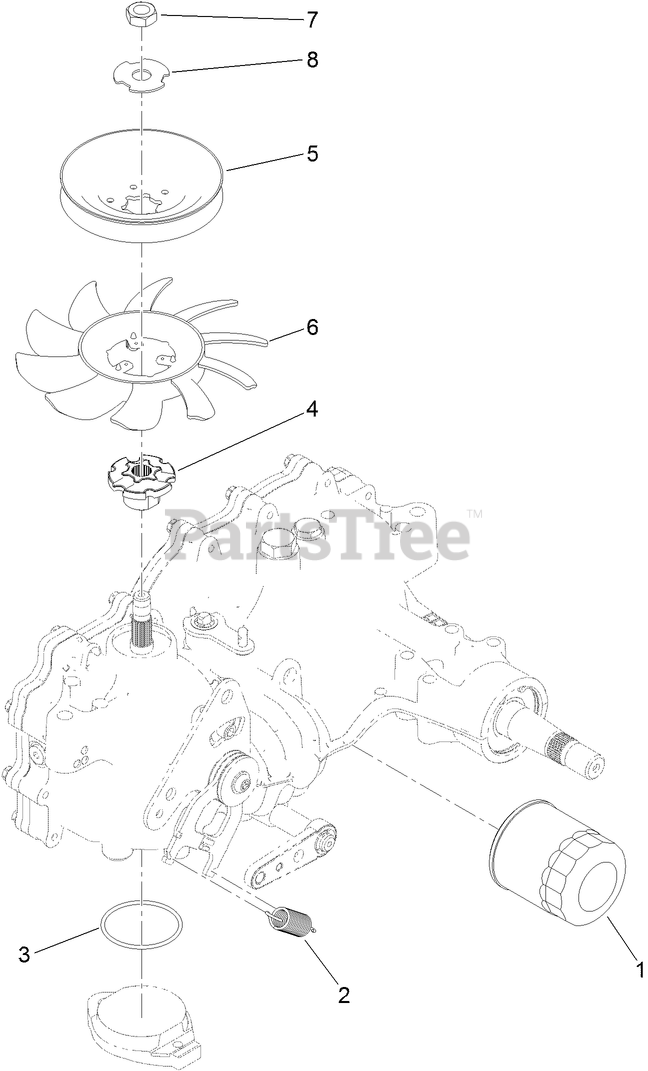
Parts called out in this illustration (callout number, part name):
1	ELEMENT-OIL FILTER, HYD
2	SPRING-EXTENSION
3	O RING-SEAL
4	HUB-PULLEY
5	PULLEY
7	NUT-HJ
8	WASHER-SLOTTED
